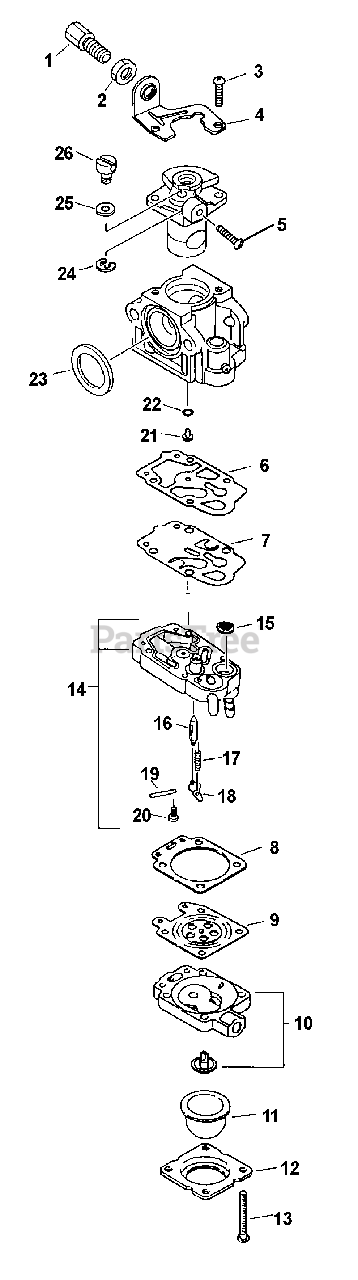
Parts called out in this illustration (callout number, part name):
1	NUT, CABLE ADJUST
4	BRACKET, THROTTLE CABLE
5	SCREW, IDLE ADJUST
6	GASKET, PURGE
7	DIAPHRAGM, PURGE
8	GASKET, METERING
9	DIAPHRAGM, METERING
10	PURGE BASE ASSY
11	BULB, PURGE
12	RETAINER, PURGE BULB
13	SCREW, PUMP COVER
14	BASE, PURGE
15	STRAINER
16	VALVE, INLET NEEDLE
17	SPRING, METERING LEVER
18	LEVER, METERING
19	PIN, METERING LEVER
20	SCREW, METERING LEVER PIN
21	JET, MAIN
23	SEAL
24	RING, RETAINING
